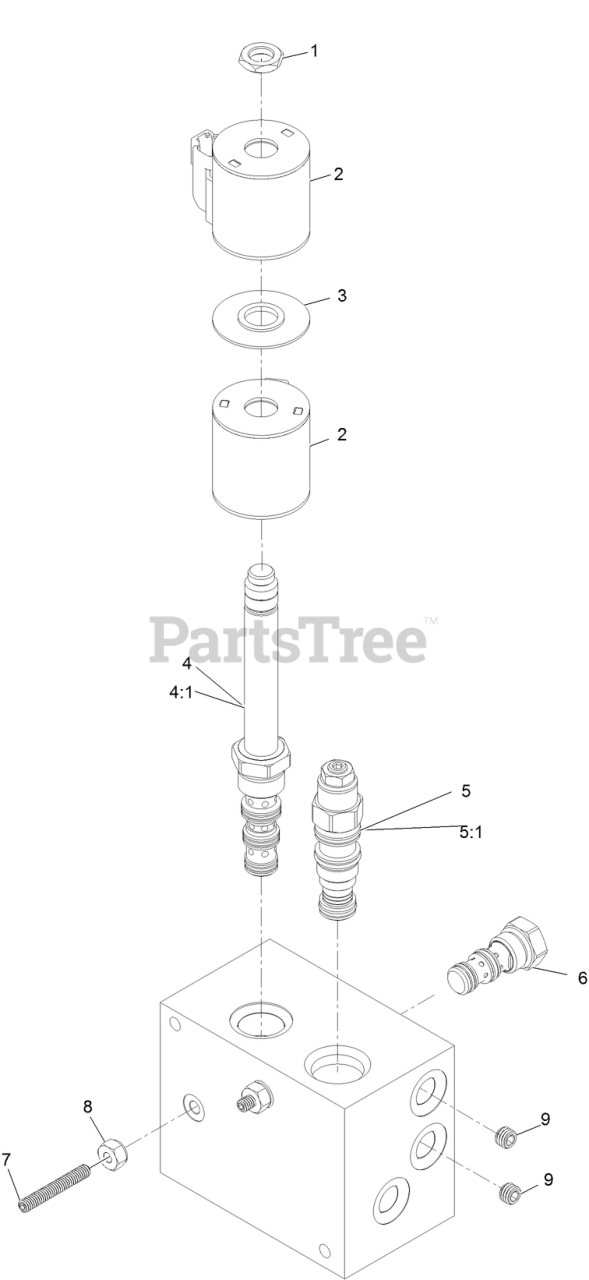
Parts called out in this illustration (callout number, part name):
1	NUT-COIL
2	COIL-12V
3	SPACER-E COIL
4	SOLENOID VALVE ASM
4:1	SPOOL VALVE SEAL KIT
5	VALVE-COUNTERBALANCE
5:1	SEAL KIT
6	VALVE-CHECK, PO
7	SCREW-SET
8	NUT-SEALING, HEX
9	PLUG-ORIFICE (0.020)
